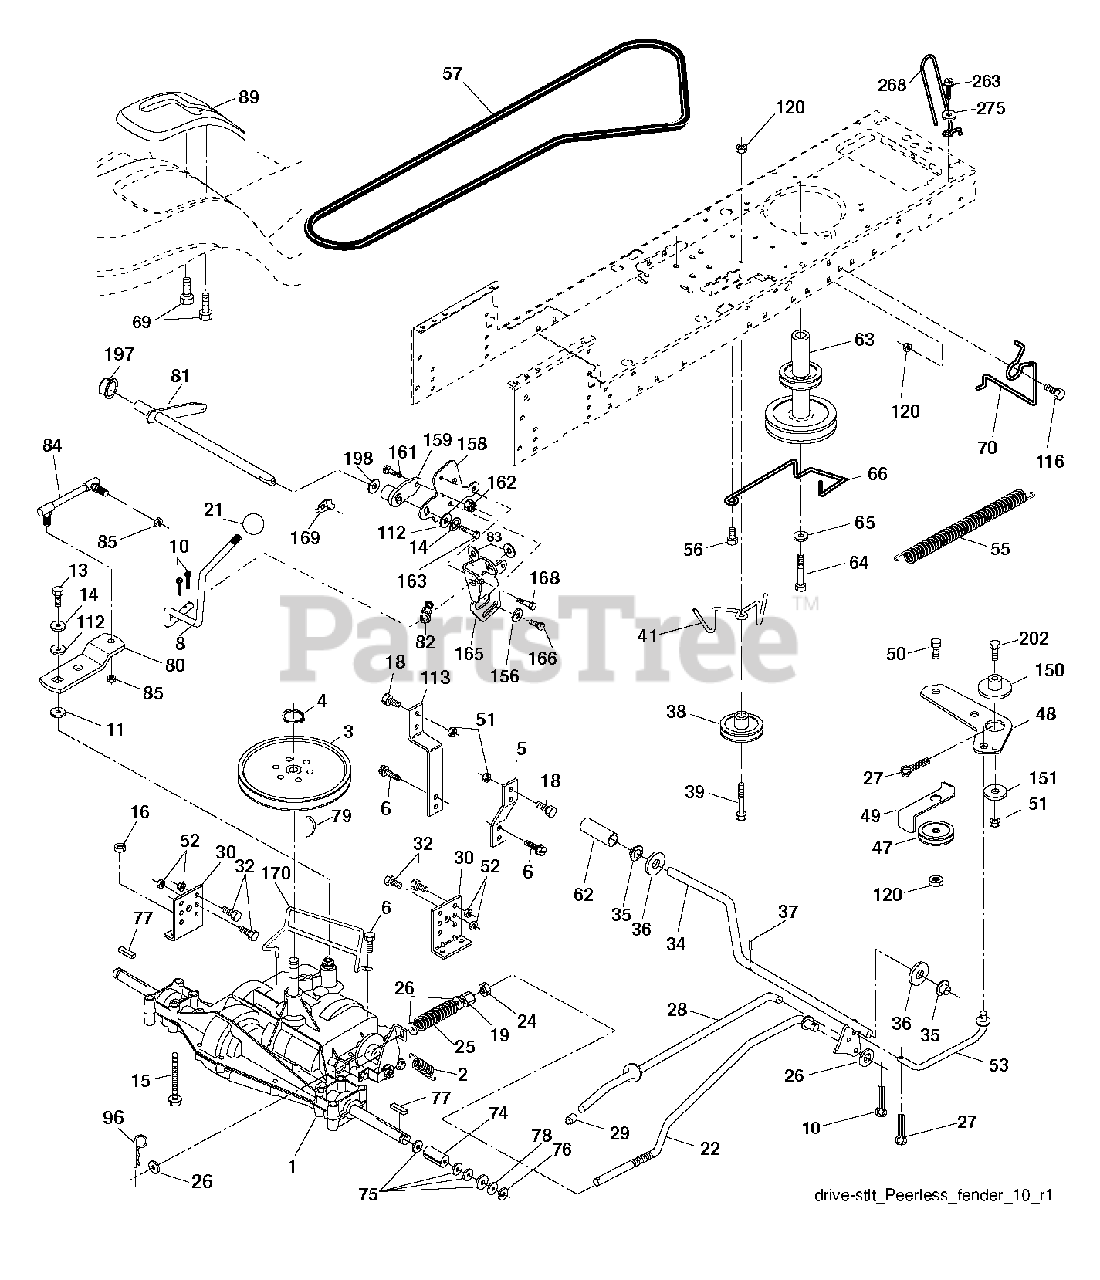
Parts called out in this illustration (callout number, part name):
2	SPRING,BRAKE RETURN
3	PULLEY TRANS
4	RETAINING RING LT
5	STRAP TORQUE
6	SCREW 5/16"
8	ROD SHIFT FENDER ADJUST LT
10	PIN COTTER
11	WASH-SHFT PLT LT
13	BOLT 1/4-28X3/4
14	LOCKWASHER
16	NUT.71038.31-18.HEX.NYLOCK
19	NUT
21	KNOB T (1/2-HOLE)
22	ROD BRAKE
24	NUT
25	SPRING ROD LT
27	COTTER PIN
28	ROD, PARKING BRAKE
29	PLUNGER CAP
30	BRKT, MOUNT TRNSAXLE
32	BOLT
34	SHAFT, FOOT PEDAL
35	BEARING.NYLON
36	WASHER LT
37	DRIVE PIN
38	PULLEY IDLER COMPOSITE
41	KEEPER, BELT IDLER
47	IDLER PULLEY
48	BELLCRANK, CLUTCH
49	RETAIN BELT
50	BOLT.3/8-16X1.50
51	LOCKNUT
52	LOCKNUT
53	LINK.CLUTCH.7.66.2005
55	SPRING, RETURN LT
56	SCREW.3/8-16
57	BELT, V GROUND DRIVE 95 25
62	PEDAL COVER T
63	ENGINE PULLEY
64	BOLT HEX 7/16-20X4-1/4"
65	LOCKWASHER
66	KEEPER BELT ENGINE
69	SCREW.HI-LO.CONSOLE
70	KEEPER BELT ENG
74	SPACER AXLE
76	E-RING LT
77	SQUARE KEY
80	ARM SHIFT
82	SHIFT SPRING
83	WASHER
85	NUT LOCK CENTER 1/4 -28 FNTHD
89	CONSOLE SHIFT STLT
96	RETAINER M
112	WASHER LT
113	STRAP TORQUE LH LT
116	BOLT D
120	NUT LOCK FLG 3/8-16 UNC
150	SPACER, RETAINER
151	WASHER 12/32X2X10GA
156	WASHER.SRRTD.5/16
158	BRACKET.SHIFT.MOUNT
159	HUB.SHIFT
161	BOLT
162	NUT.CROWNLOCK.1/4
165	BRACKET.PIVOT.LEVER
168	BOLT.SHOULDER.5/16-18X
169	PLATE.FASTENING.CROSS.SHAFT
170	KEEPER BELT T/A
197	NYLINER SNAP 5/8" ID
198	WASHER.NYL.7/8IDX.105"HYD CR
202	BOLT
263	SCREW, 3/8-16X3/4
275	WASHER
